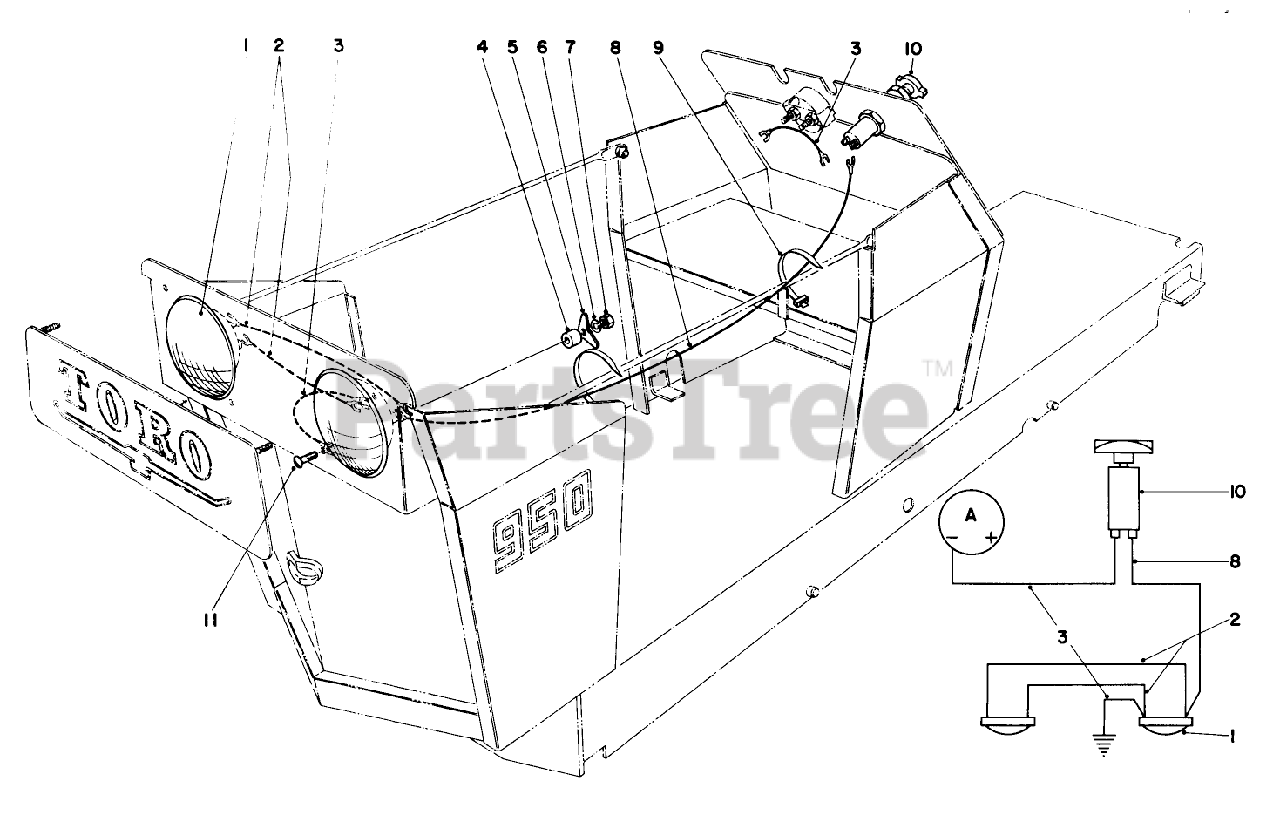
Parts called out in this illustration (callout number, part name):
1	HEAD LAMP
2	Wire 960
3	Wire 12 H.P.
4	Spacer
5	Clip 960
6	WASHER-LOCK/SP
7	NUT-HEX
8	Wire 960
10	Light Switch
11	SCREW-SRH
